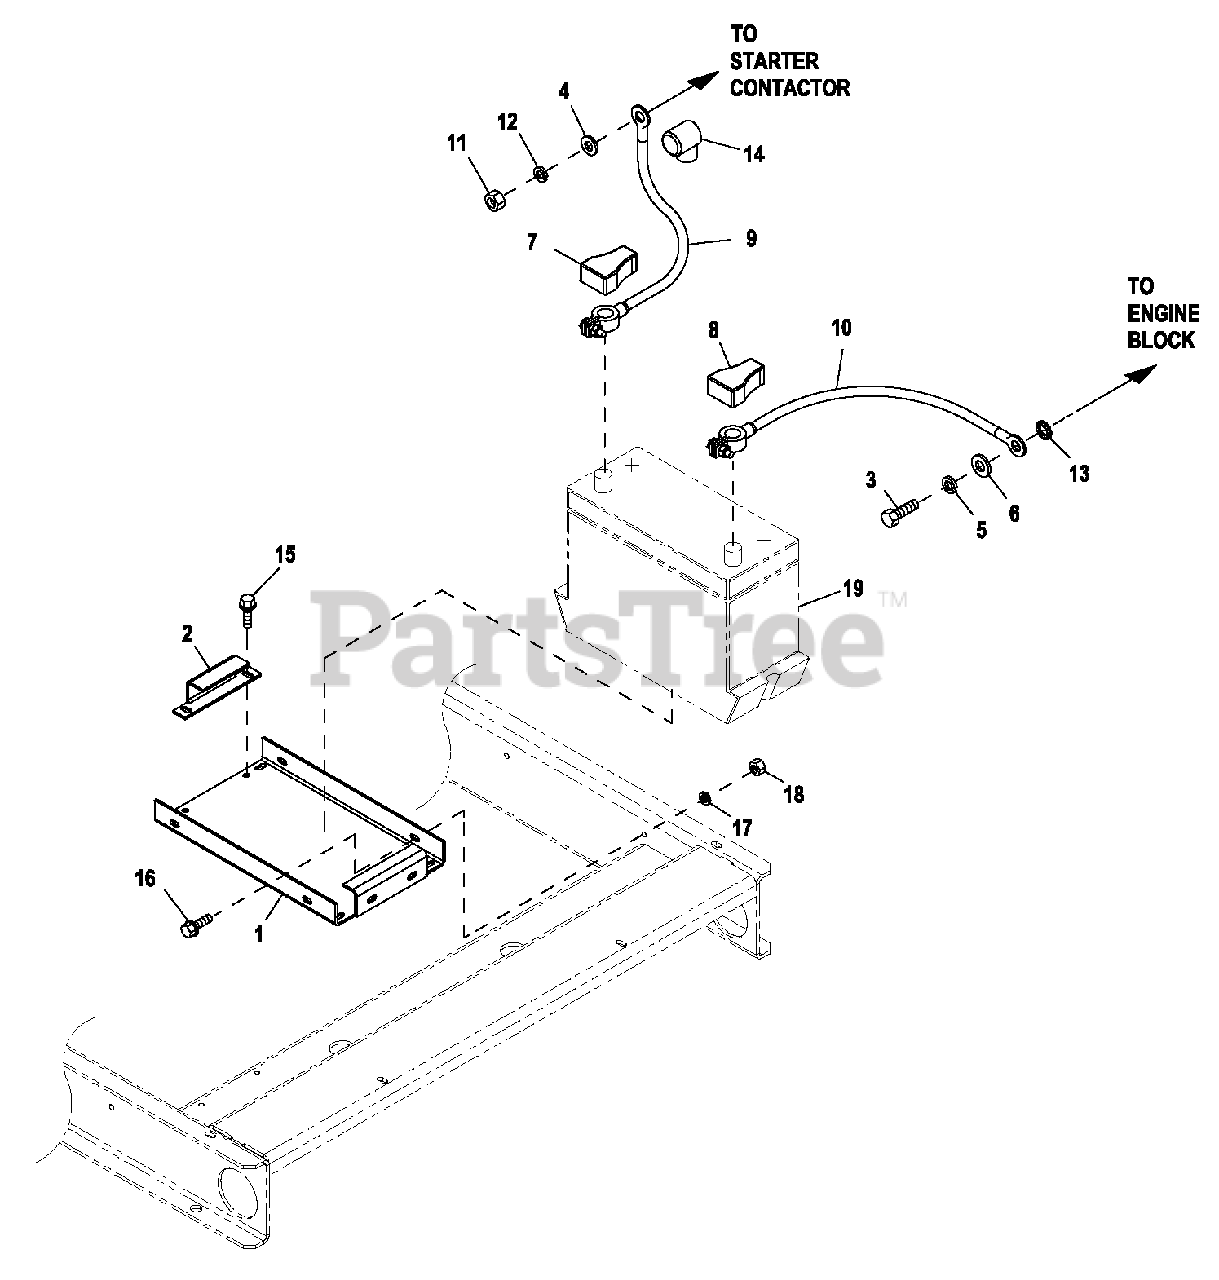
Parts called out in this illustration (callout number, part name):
1	TRAY BATTERY
2	STRAP BATTERY RETAINMENT
3	SCREW HHC M12-1.75 X 25 G8.8
4	WASHER FLAT 5/16-M8 ZINC
5	WASHER LOCK 1/2
6	WASHER FLAT 1/2 ZINC
7	BATTERY POST COVER RED &
8	BATTERY POST COVER BLACK -
9	CABLE BATT RED #1X28.00
10	CABLE BATT BLK #1 X 16.00 NEG
11	NUT HEX M8-1.25 G8 YELCHR
12	WASHER LOCK M8-5/16
13	WASHER SHAKEPROOF EXT 7/16 STL
14	BOOT CONTACTOR CABLES
15	SCREW THF M6-1 X 16 N WA Z/JS
16	SCREW HHC M6-1.0X20 G8.8
17	WASHER LOCK M6-1/4
18	NUT HEX M 6X1.0 G8 YELCHR
19	BATT 12VDC 24F 525 CCA (SOLD AS AN OPTION)
